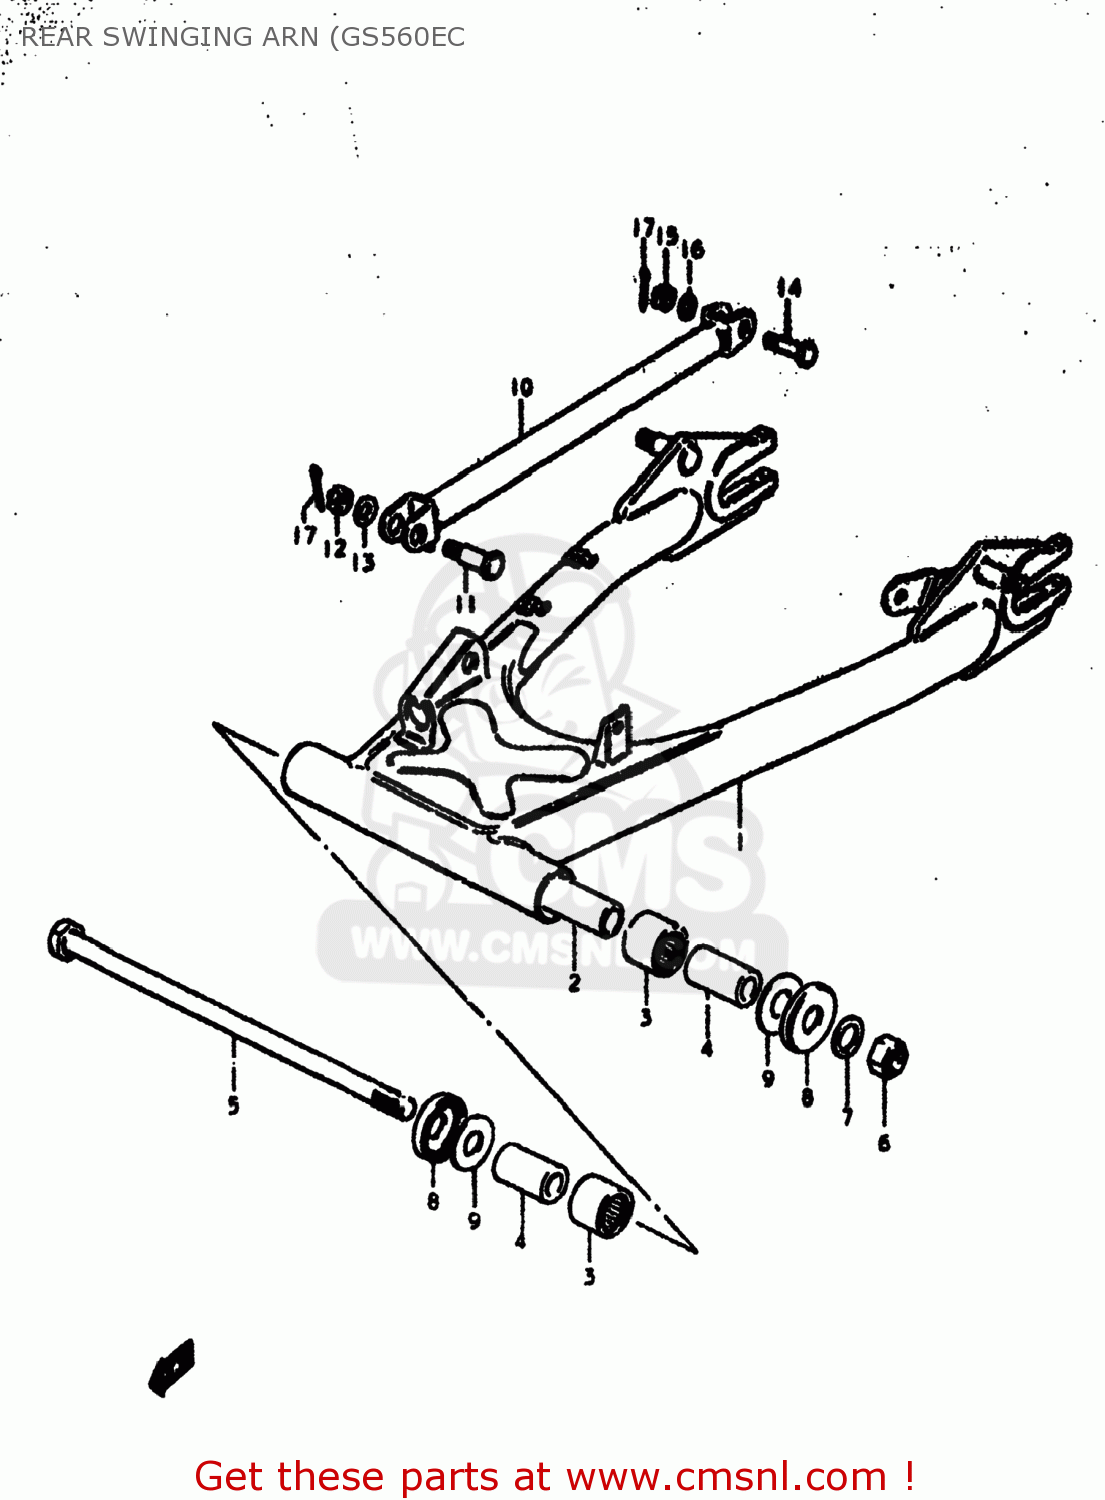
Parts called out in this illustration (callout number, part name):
1	SWING ARM ASSEMBLY,REAR
2	SPACER,SWING ARM,CENTER
3	BEARING(22X29X30)
4	SPACER,RR SWGARM PIVOT
5	SHAFT,REAR SWING ARM
6	NUT 14MM
7	WASHER
8	COVER,REAR SWING ARM DUST
9	WASHER(14.2X34X1)
10	LINK,REAR TORQUE
11	BOLT
12	NUT
13	WASHER
14	BOLT(10X39)
15	NUT
16	WASHER
17	PIN 20X20
